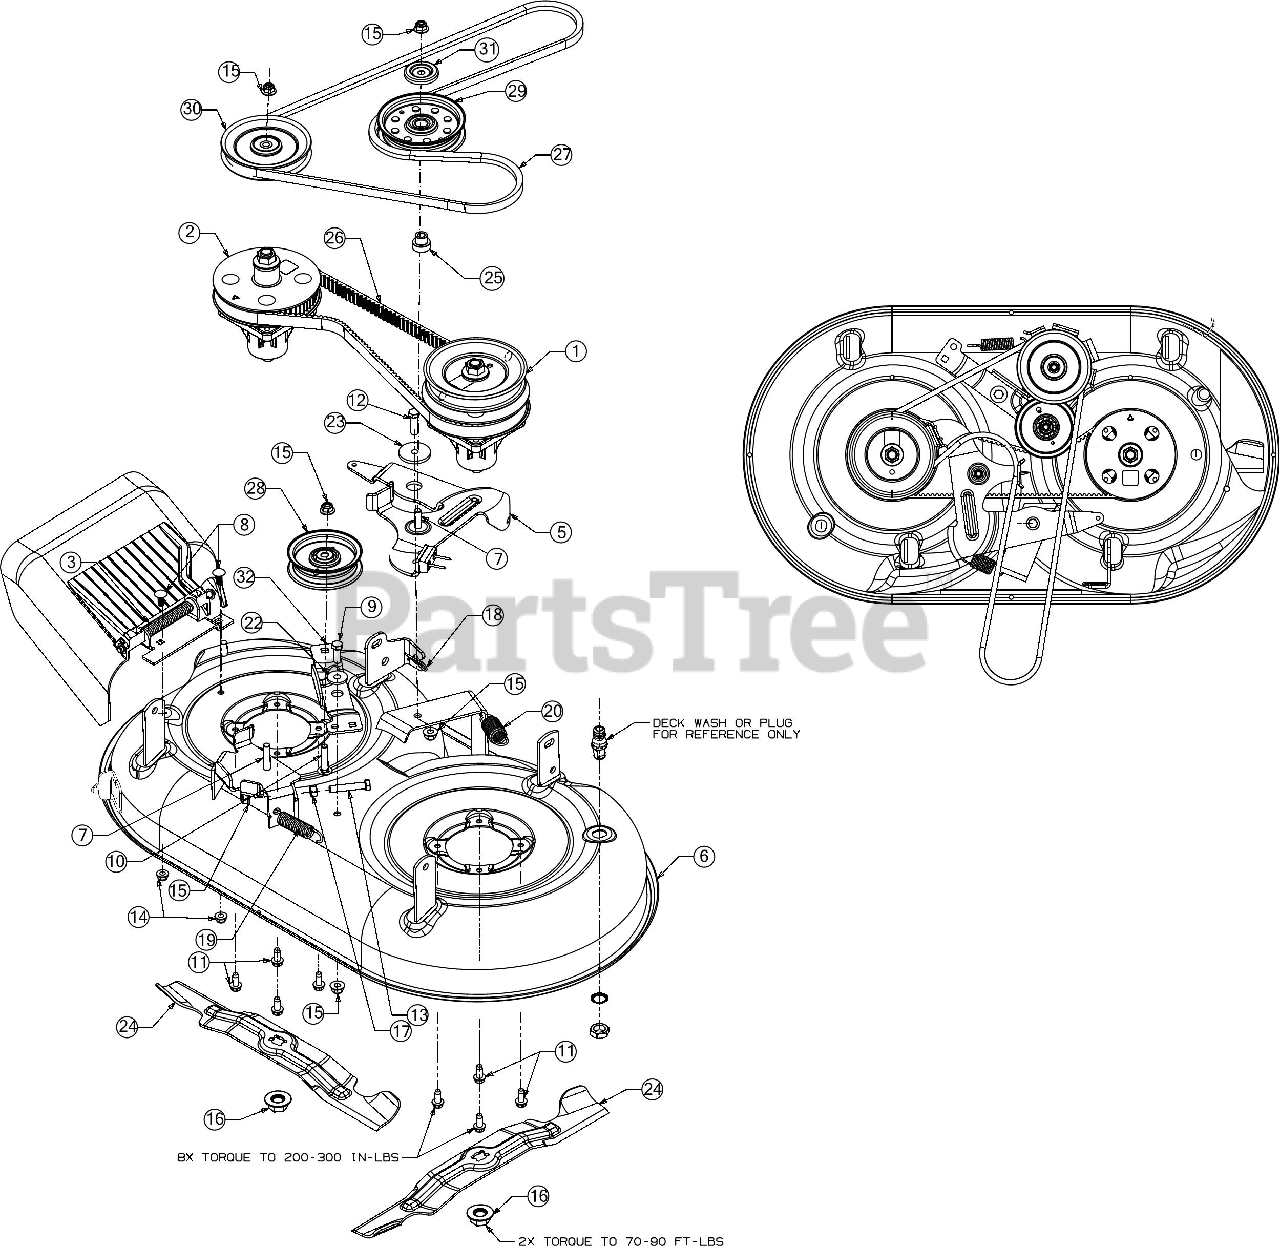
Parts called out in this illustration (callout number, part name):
1	SPINDLE ASSEMBLY
1	SCREW 1/4-10:.625
1	TIMING PULLEY
1	FLAT WASHER
1	THRUST WASHER .793X1.368X
1	SPINDLE SHAFT
1	DECK SPINDLE SPACER
1	SPACER- .792 X 1.060 X 1.860
1	DECK PULLEY
1	TIMING PULLEY PLATE
1	BALL BEARING
1	FLANGE NUT 5/8-18
2	SPINDLE ASSEMBLY
2	SCREW 1/4-10:.625
2	TIMING PULLEY
2	FLAT WASHER .793ID X 1.24OD X .060
2	FLAT WASHER
2	SPINDLE SHAFT
2	DECK SPINDLE SPACER
2	SPACER- .792 X 1.060 X 1.860
2	TIMING PULLEY PLATE
2	BALL BEARING
2	FLANGE NUT 5/8-18
3	33" DISCHARGE CHUTE ASSEMBLY
5	IDLER ARM ASSEMBLY
6	33" DECK ASSEMBLY
7	HEX SCREW 3/8-16 X 1.75 GR5
8	CARRIAGE BOLT 5/16-18 X .75
9	SCREW 3/8-16 X 1 GR5
10	BOLT 3/8-16 X 1.69 GR5
11	SCREW 5/16-18 X .750
12	SCREW 3/8-16 X 1.25 GR5
13	SCREW 3/8-16 X 2 GR5
14	FLANGE LOCK NUT 5/16-18
17	HEX NUT
18	INTERNAL COTTER PIN
19	EXTENSION SPRING TIMING BELT
20	EXTENSION SPRING
22	SHOULDER SPACER
23	SHOULDER SPACER
24	17.9" BLADE
25	SHOULDER SPACER
26	TIMING BELT .315 X 787 160T"
27	SPINDLE BELT A X 72.2
28	IDLER PULLEY
29	IDLER PULLEY 4.25 DIA
30	V-IDLER PULLEY
31	IDLER PULLEY CAP
32	TIMING IDLER BRACKET
